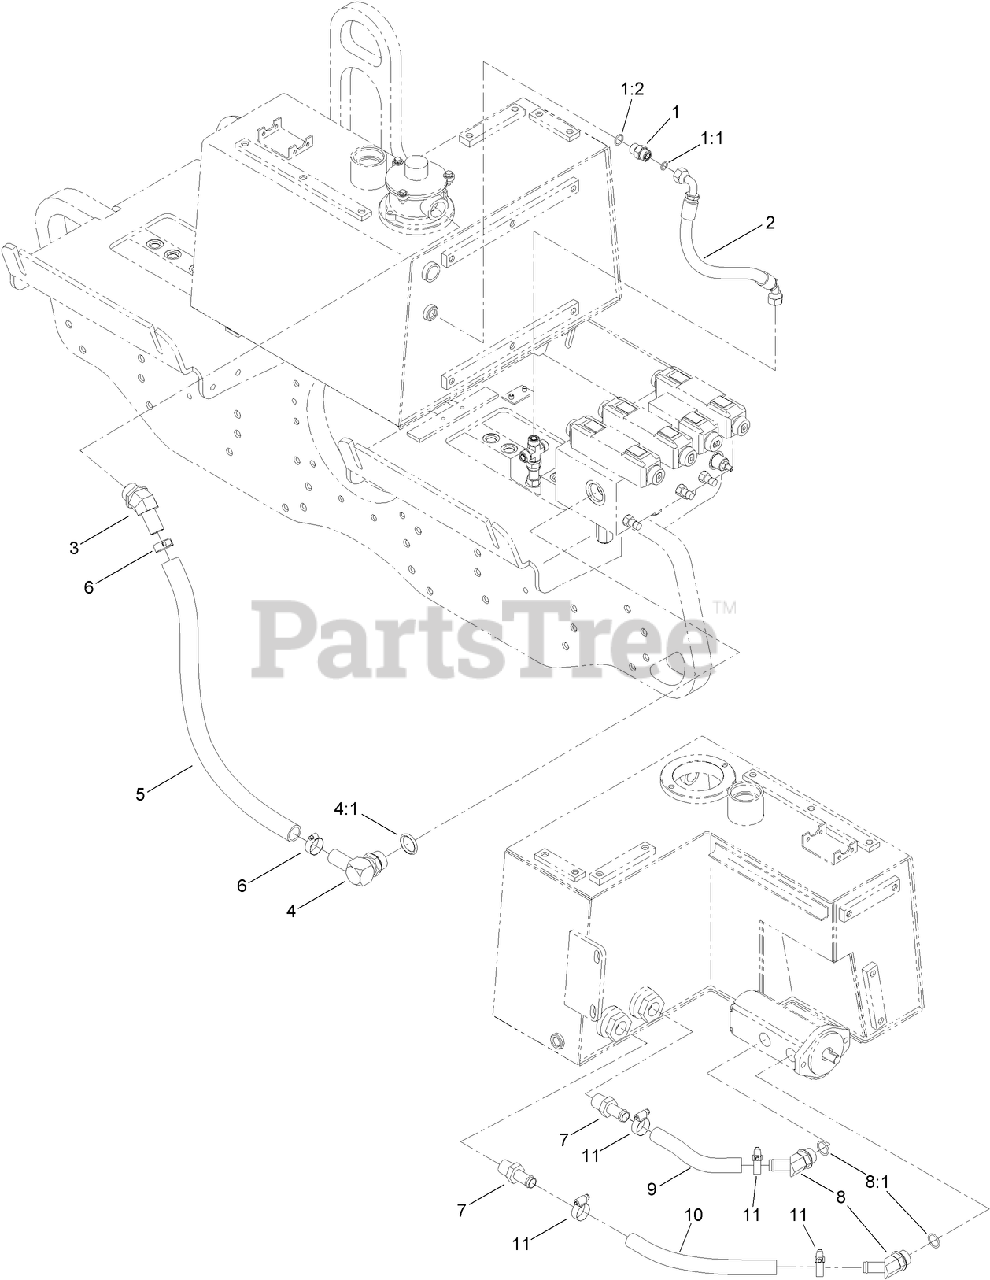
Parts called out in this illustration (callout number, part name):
1	FITTING-STRAIGHT
1:1	O-RING
1:2	O-RING
2	HOSE ASM
3	ELBOW-45 DEG
4	STEM-BARB-90
4:1	O-RING
6	CLAMP-HOSE
7	FITTING-HYD
8	ELBOW-45 DEG
8:1	O-RING
11	CLAMP-HOSE
